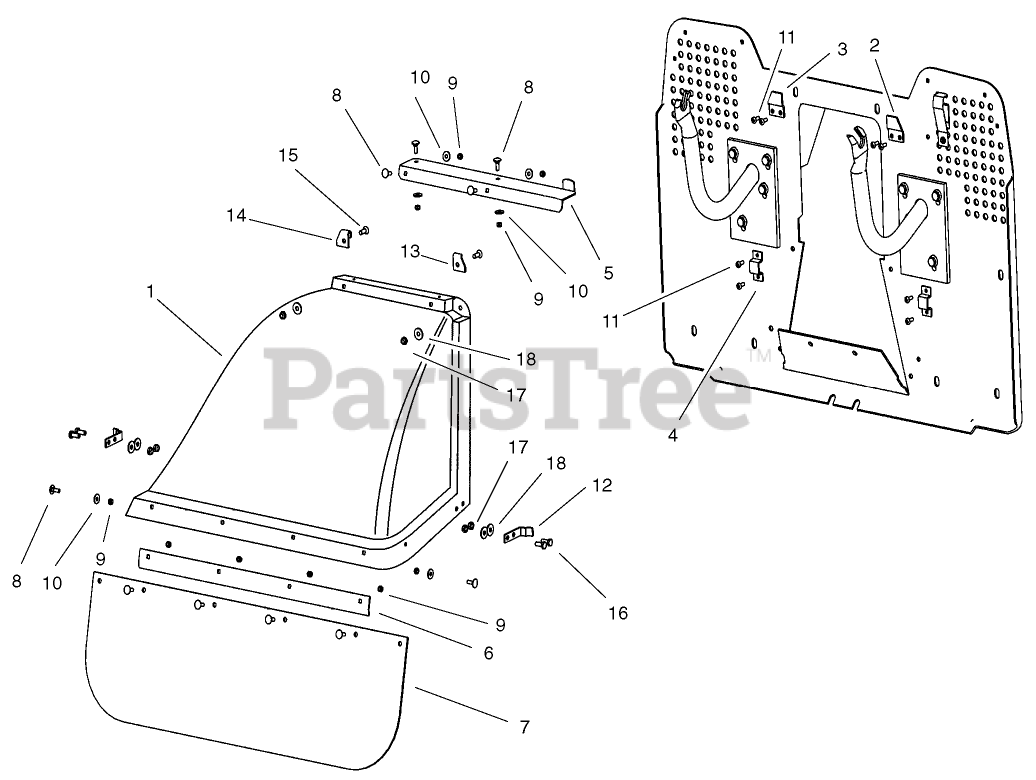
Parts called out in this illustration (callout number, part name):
1	Deflector
2	Bracket-Right
3	Bracket-Left
5	Crossbar
7	Shield
8	BOLT-CARRIAGE
9	NUT-LOCK
10	WASHER-FLAT
12	Clip-Deflector
13	Holder-Right
14	Holder-Left
16	SCREW-HH
17	NUT-LOCK
18	Washer
